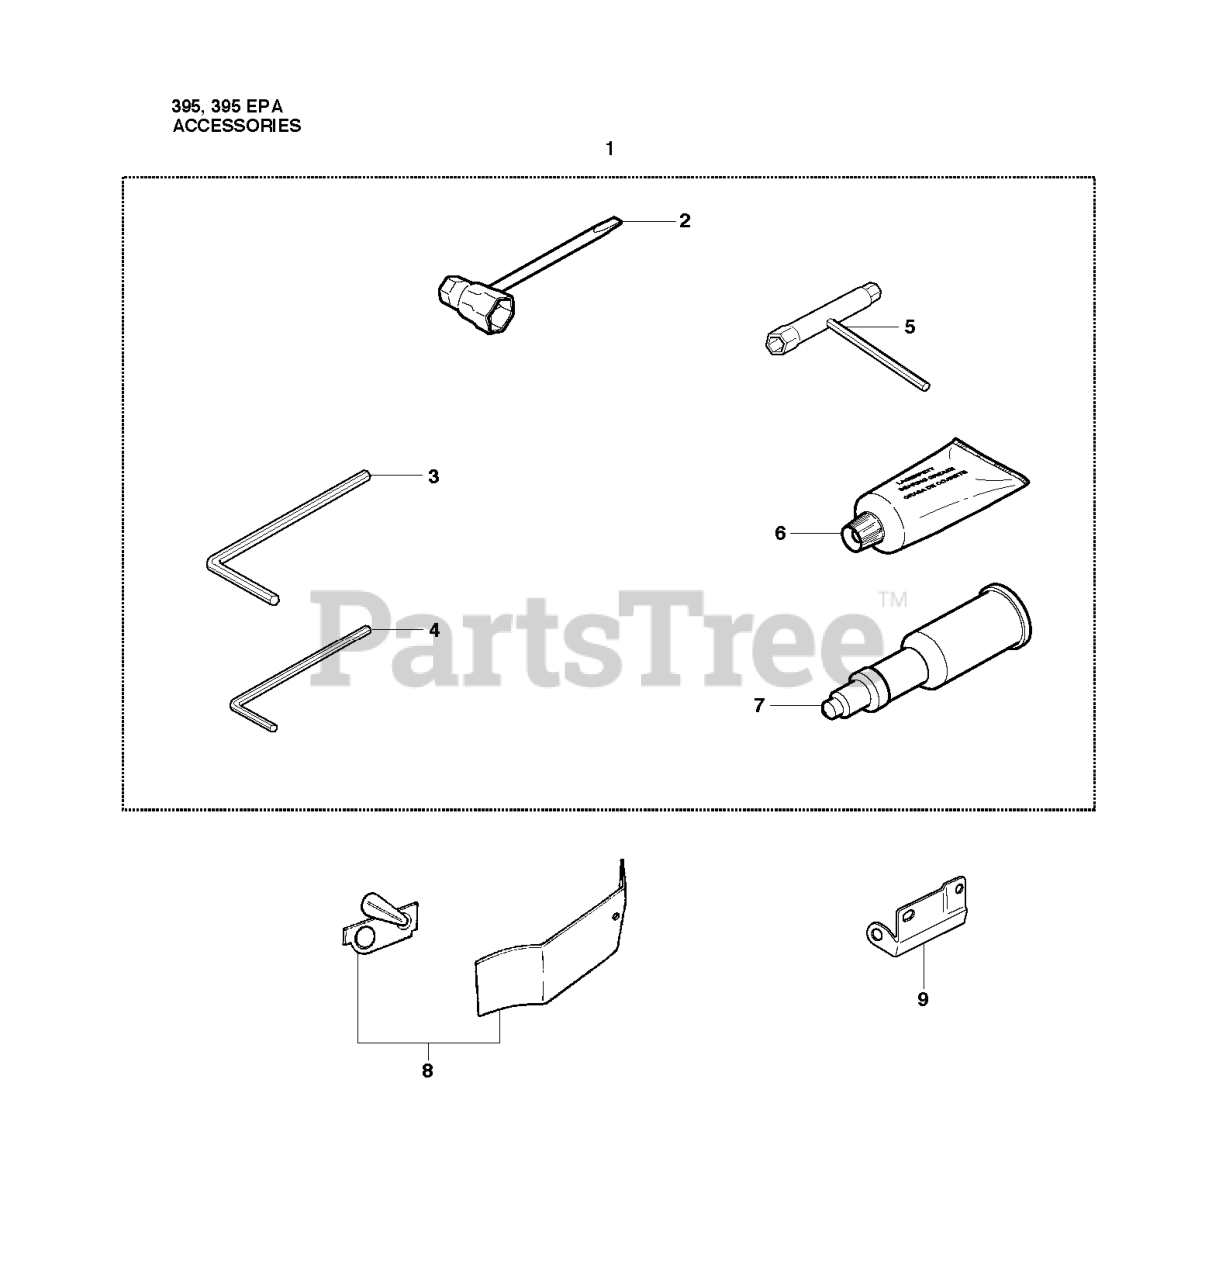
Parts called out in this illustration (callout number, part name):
2	COMBI TOOL
5	COMB.TOOL 8-10-14
6	GREASE
7	Grease Gun
8	WINTER KIT
